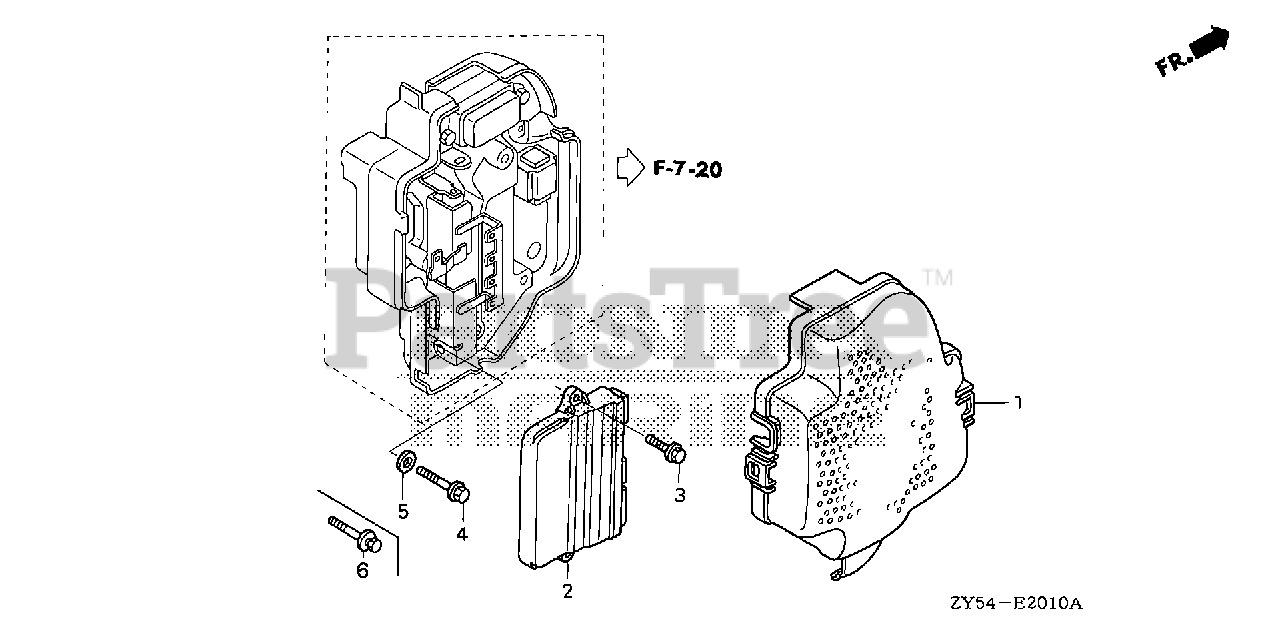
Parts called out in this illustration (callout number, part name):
1	COVER, ELECTRONIC PARTS
2	CONTROL UNIT, ELECTRONIC
3	BOLT, FLANGE (6X20)
6	BOLT-WASHER (6X27) (CT200)
